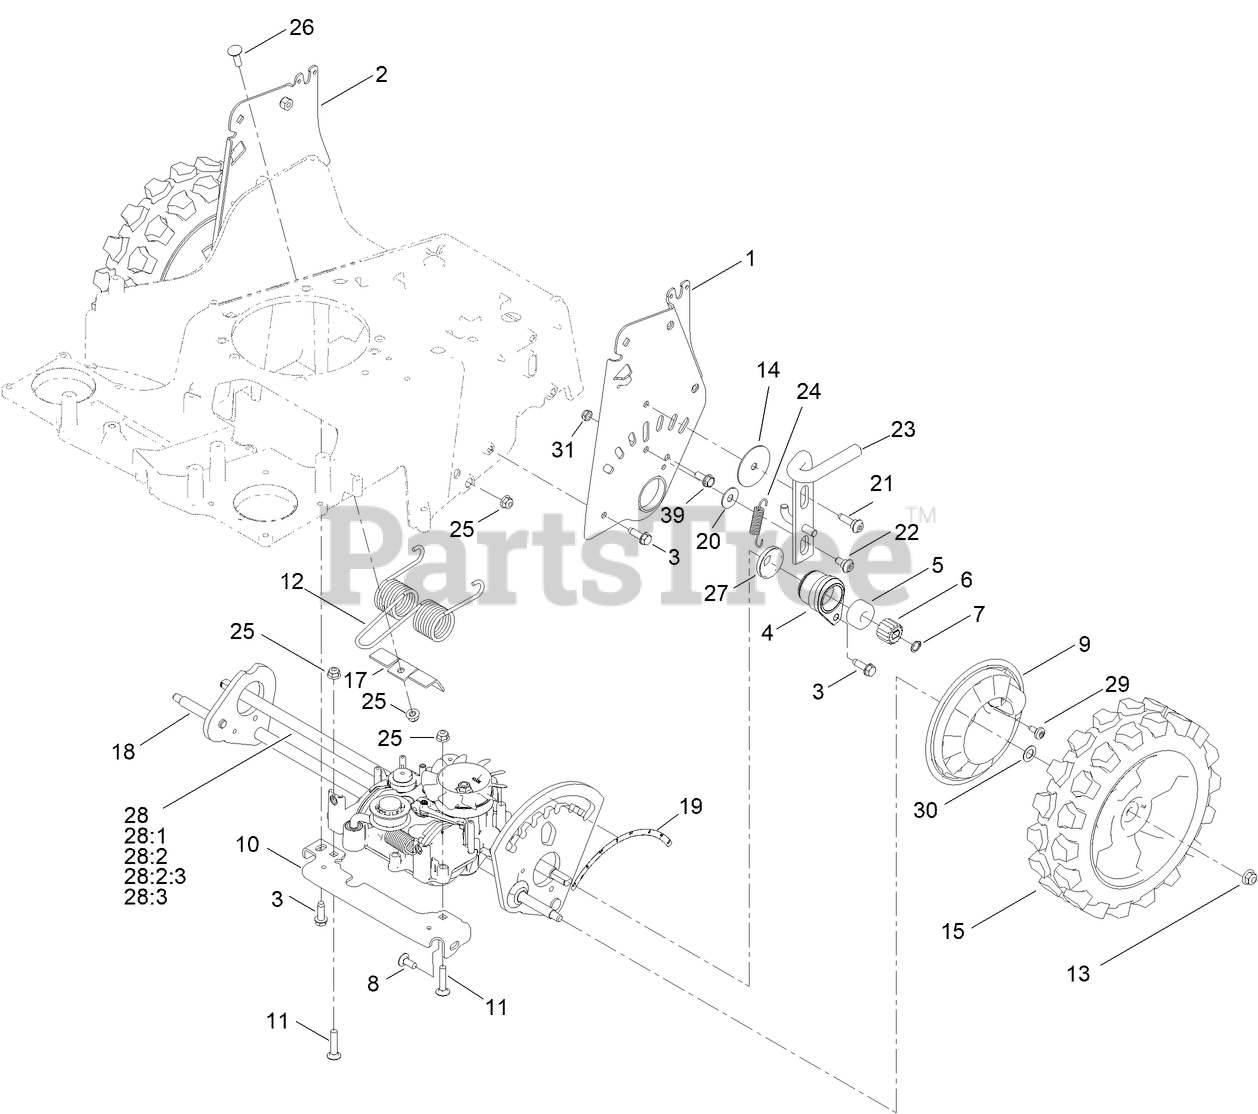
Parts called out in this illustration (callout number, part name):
1	HOC PLATE ASSEMBLY
2	HOC PLATE ASSEMBLY
3	SCREW-THD ROLL, HWH
4	BEARING RETAINER ASM
5	BEARING-BALL, CUSTOM
6	GEAR-PINION, 15T
7	RING-RETAINING
8	SCREW-CARR
9	COVER-WHEEL
10	BRACKET-TRANSMISSION, FRONT
11	BOLT-CARR
12	SPRING-TORSION
13	NUT-HF, NI
14	WASHER-PLAIN
15	10.5 IN. WHEEL ASM
17	BRACKET
18	REAR AXLE ASM
19	DECAL-HOC, REAR
20	WASHER
21	SCREW-SHOULDER, BHTF
22	BOLT-SHOULDER
23	LOCK-HEIGHT, ADJ
24	SPRING-EXTENSION
25	NUT-HF, NI
26	BOLT-CARR
27	COVER-BEARING
28	TRANSMISSION-MV702
28:1	PULLEY FAN REPAIR KIT
28:2	IDLER PULLEY REPAIR KIT
28:2:3	SPRING-TENSION, BELT
28:3	CLUTCH LEVER REPAIR KIT
29	SCREW-SHOULDER
30	WASHER-PLAIN
31	NUT-LOCK, NI
39	SCREW
